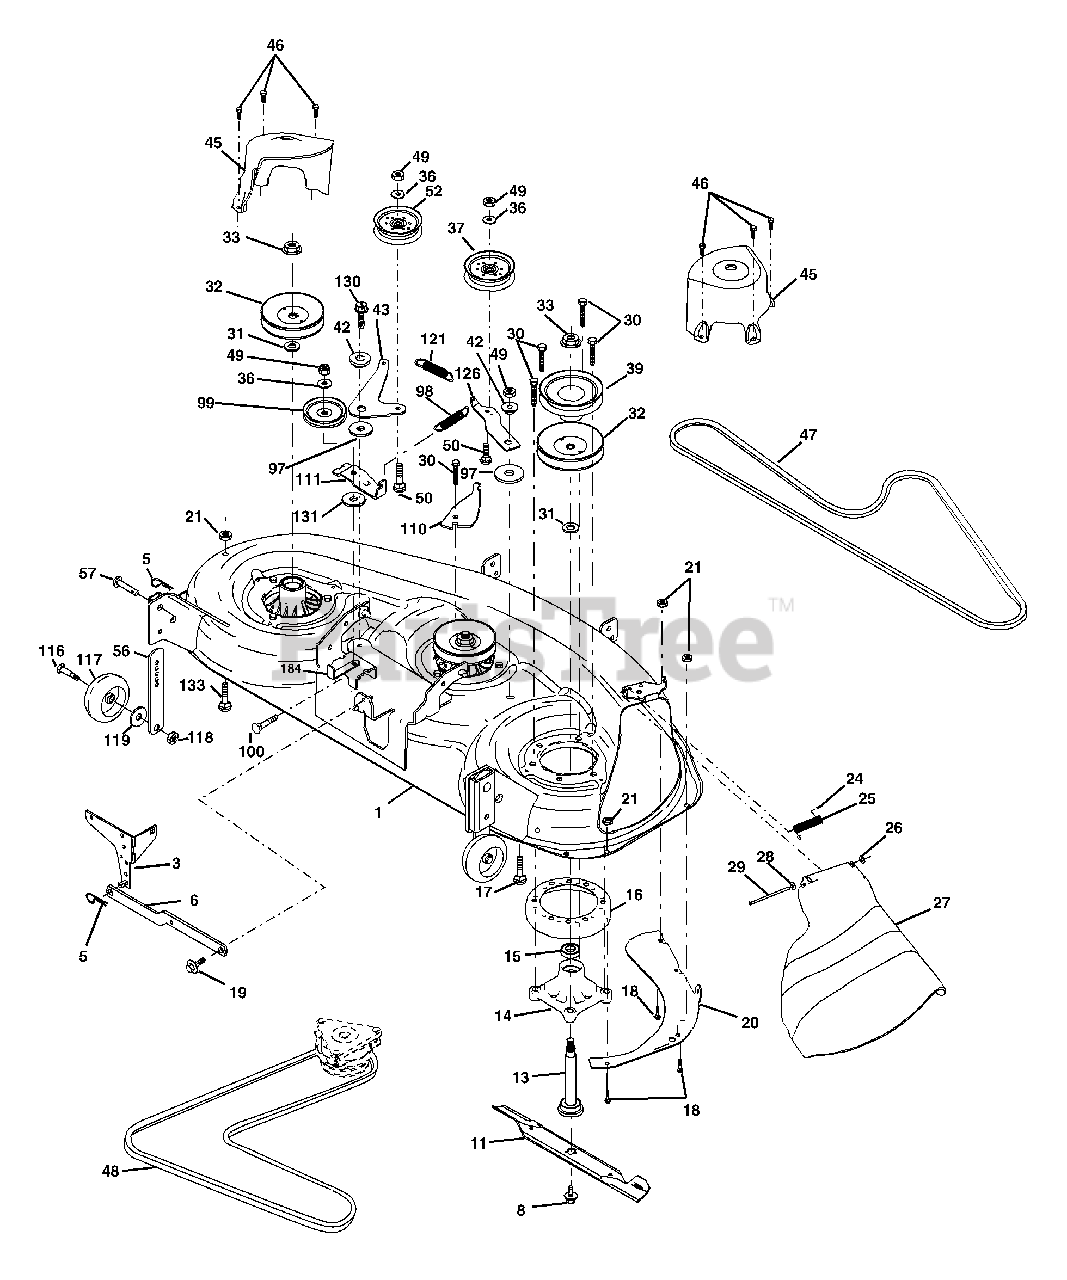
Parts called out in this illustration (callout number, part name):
1	Deck Weldment Mower 48
3	Bracket Asm., Sway Bar
5	Retainer Spring
6	Arm, Suspension, Rear Sway Bar Deck
8	Bolt 7/16 Asm. Blade
11	Blade
13	Shaft Asm. w/Lower Bearing
14	Mandrel Asm. Housing
15	Bearing, Ball, Mandrel
16	Stripper Mandrel Deck
17	Bolt RDHD Sq Neck 3/8-16 x 1.25
18	Bolt, Carriage 5/16-18 x 5/8
19	Bolt, Hex Hd, Shoulder 5/16-18
20	Baffle, Vortex Mower
21	Nut, Crownlock 5/16-18 UNC
24	Cap, Sleeve
25	Spring, Torsion
26	Nut, Push
27	Deflector Shield
28	Washer 11/32 x 5/8 x 16 Ga.
29	Rod, Hinge
30	Screw, Thdroll Washer Head
31	Washer, Spacer Mower Vented
32	Pulley, Mandrel
33	Nut, Flg. Top Lock Cntr. 9/16
36	Washer 13/32 x 13/16 x 16 Ga.
37	Pulley, Idler, Flat
39	Pulley, Idler, Driven
42	Spacer, Retainer
43	Arm, Idler Secondary
45	Cover, Mandrel Deck
46	Screw, Thdroll. 1/4-20 x 5/8
47	V-Belt, Mower, Secondary
48	V-Belt, Mower, Primary
49	Nut, Crownlock 3/8-16 UNC
50	Bolt, Carr. 3/8-16 x 1-1/2 Gr. 5
52	Pulley Idler Flat
56	Bar Pnt Adj.
57	Pin Head Rivet
97	Washer Hardened
98	Spring Primary Drive
99	Pulley Idler "V"
100	Bolt RDHD Sqnk 3/8-16 UNC x 2
110	Arm Spring Secondary
111	Arm Spring Fixed Tension
116	Bolt, Shoulder
117	Gauge Wheel
118	Nut, Centerlock 3/8-16 UNC
119	Washer 3/8 x 7/8 x 14 Ga.
121	Spring Secondary Drive
126	Arm, Idler, Primary Deck
130	Screw 3/8-16 x 1.0
131	Washer 13/32 x 1.00 x 6 Ga.
133	Bolt RDH SQNK 5/16-18unc x 3/4
184	Keeper Belt Idler
